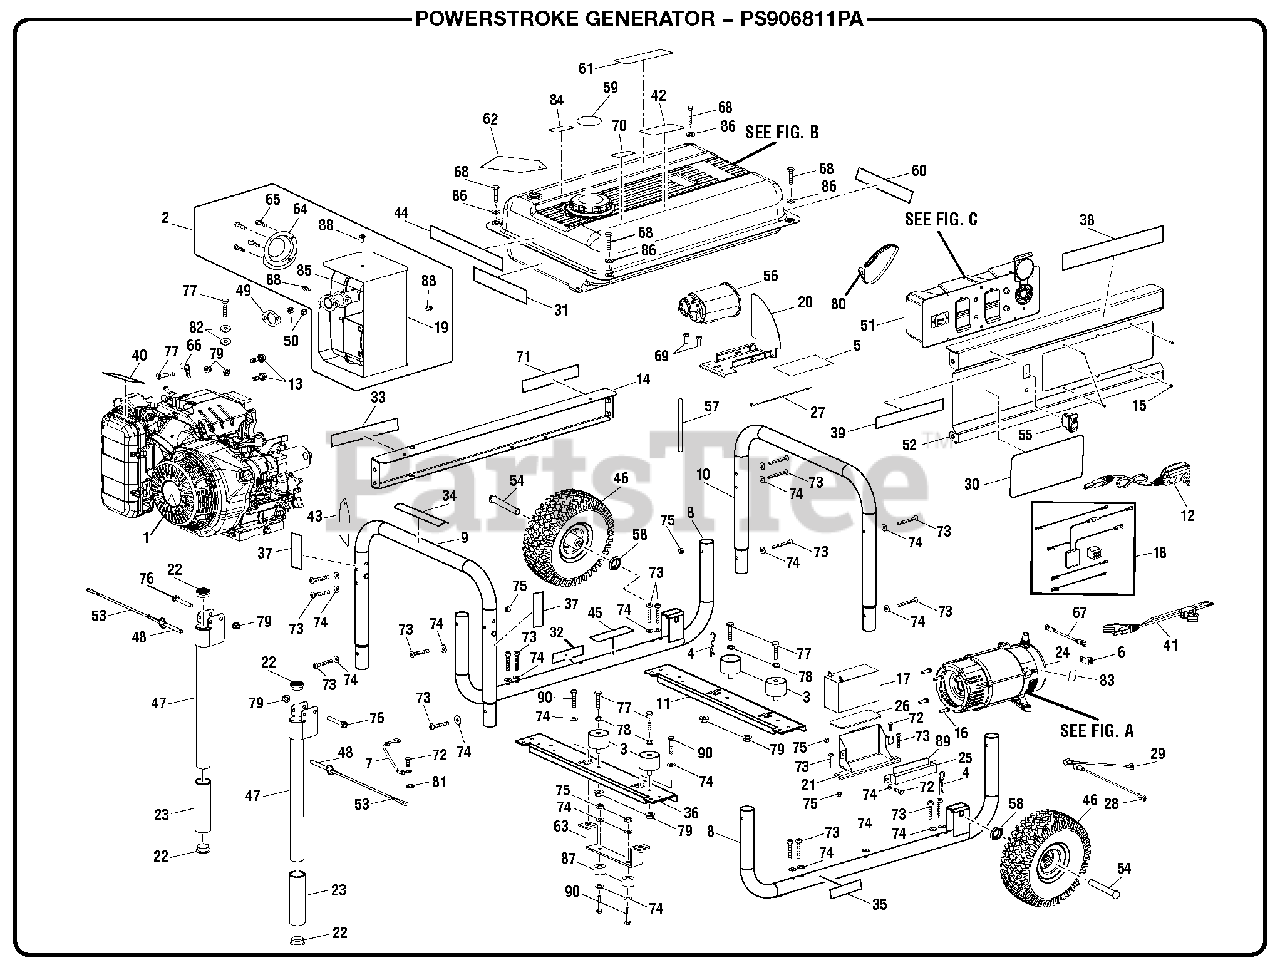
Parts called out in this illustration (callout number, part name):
2	Muffler Assembly
4	Hitch Pin
5	Rubber Sheet
6	Ground Lug
7	Ground Wire Assembly
8	Lower Frame Assembly
9	Tube Assembly (Left)
10	Tube Assembly (Right)
11	Cross Brace (Generator Head)
12	Battery Charger
13	Bolt (5/16-24 x 5/8 in.)
14	Back Panel
15	Screw (6-20 x 3/8 in.)
16	Bolt (3/8-16 x 1-1/4 in.)
17	Battery
18	Wire Harness
19	Heat Shield
20	Bracket (Carbon Canister)
21	Battery Box Gasket
23	Handle Grip
24	Generator Head (See Figure A)
25	Battery Hold Down Bracket
26	Gasket (Battery Hold Down Bracket)
28	Battery Cable (Red)
29	Battery Cable (Black)
30	Performance Label
31	Electric Start Label
32	Hot Surface Label
33	Danger Label
34	Fire Danger Label
35	Engine Lubricant Label
36	Cross Brace (Engine)
37	Locking Pin Label
38	Honda Label
39	Electric Start Label
40	Choke Label
41	Pigtail (DC)
42	CPSC Label
43	Danger Hang Tag
44	Inquires Label
45	Combustion Warning Label
47	Handle Assembly
48	Release Pin (5/16 x 2 in.)
49	Exhaust Gasket
51	Control Panel Assembly (See Figure C)
52	Front Panel
55	Start Switch w/Lock
56	Carbon Canister Assembly
57	Purge Hose
58	Washer (1/2 in.)
59	Fuel Stabilizer Label (English)
60	Ground Warning Label
61	Fuel Warning Label
63	Foot Bracket
64	Spark Arrestor
65	Screw (8-32 x 3/8 in., Pan Hd.)
66	J-Clamp (1/2 in.)
67	Bonding Wire
68	Screw (1/4-14 x 1-1/4 in.)
69	Screw (#10-16 x 3/4 in.)
70	E85 Label
71	Fire Distance Label
72	Screw (M6 x 16 mm, Hex Hd.)
73	Screw (M6 x 50 mm, T30 Torx Pan Hd.)
74	Washer (M6)
75	Lock Nut (M6)
76	Bolt (M8 x 55 mm, Hex Hd.)
77	Bolt (M8 x 35 mm, Hex Hd.)
78	Washer (M8)
79	Flange Lock Nut (M8 x 1.25)
80	Cable Tie (18.6 in.)
81	Star Washer (M6)
82	Washer (5/16 in)
83	Ground Label
84	Fuel Stabilizer Label (Spanish)
85	Muffler w/Brackets
86	Washer (1/4 in.)
87	Rubber Foot
88	Bolt (M6 x 9 mm)
89	Battery Bracket Gasket
90	Bolt (M6 x 25 mm, Hex Hd.)
